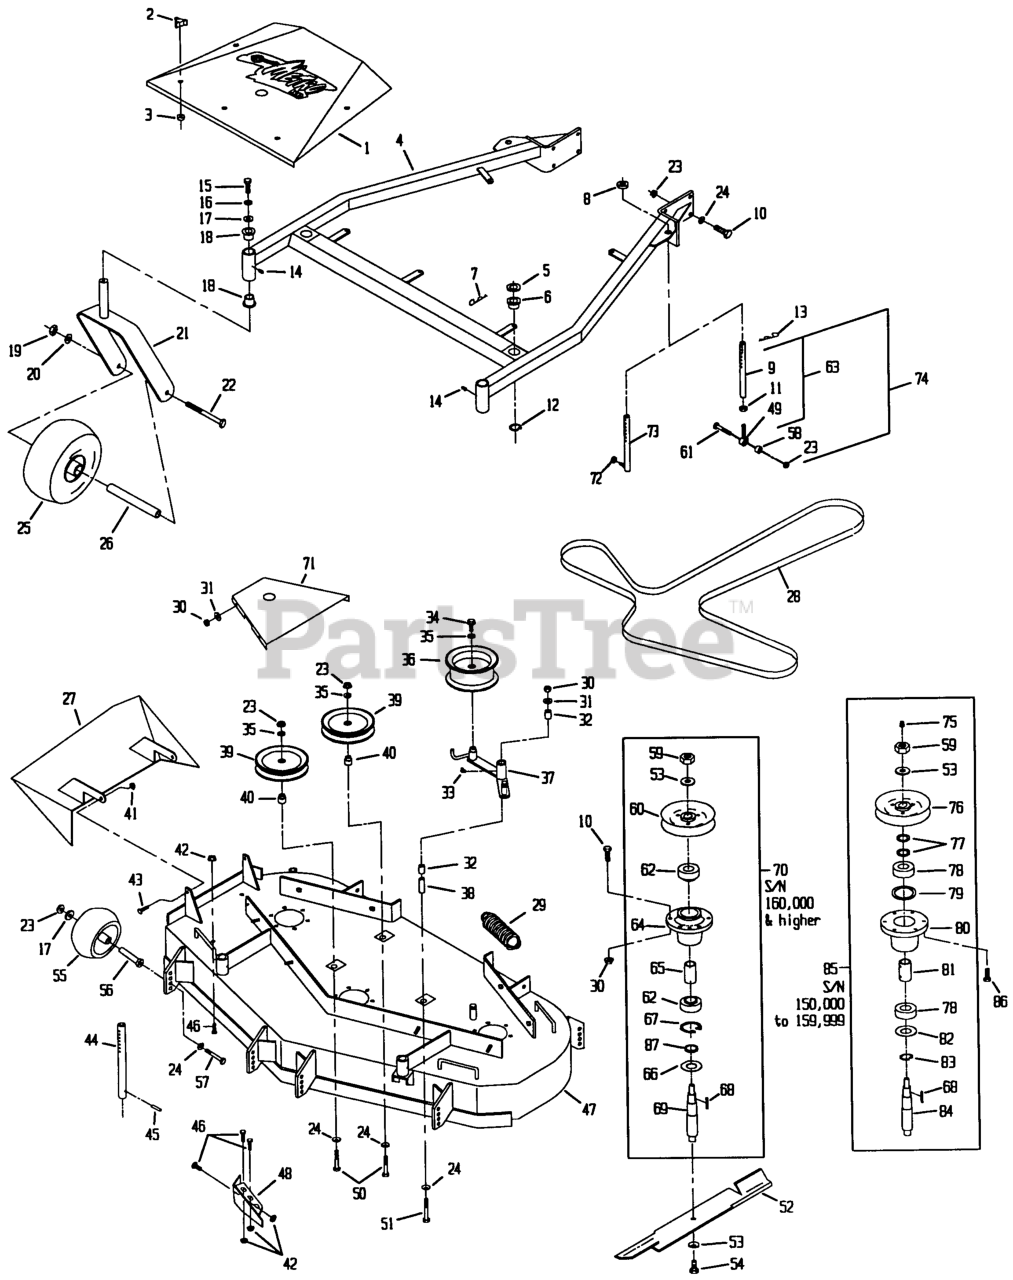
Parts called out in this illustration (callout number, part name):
1	SHIELD W/DECAL,MHP52
2	KNOB-3 PRONG
4	SUPPORT,DECK W/BUSHINGS
5	SPACER-DECK SUPPORT
6	BUSHING-DECK
9	LINK, DECK SUPPORT
13	PIN,HAIR COTTER
18	BEARING-FLANGED
27	WLD,CHUTE DISCHARGE
28	BELT,DECK DRIVE
32	SLEEVE-BEARING
38	BUSHING-PIVOT, IDLER
39	PULLEY-IDLER
40	BUSHING-IDLER
44	ROD,DECK SUPPORT
47	ASM,DECK W/DECALS TTHP52
48	WLD,BAFFLE DISCHARGE
49	BALLJOINT
51	SCREW-HH
53	WASHER-SPRING
55	ROLLER-SCALP, ANTI
56	BUSHING-ROLLER
60	SHEAVE,W/HUB 5.72
62	BEARING
65	SPACER-BEARING
66	GUARD-BEARING, BOTTOM
68	KEY-RECTANGLE
69	SHAFT,SPINDLE
70	HOUSING,CUTTER COMPLETE
73	Link
76	SHEAVE,W/HUB 5.72
77	WASHER-SPACER
78	BEARING,HD SPINDLE
79	O-RING
80	HOUSING,BEARING
81	SPACER,BEARING
82	SEAL,MECHANICAL DUST
83	RING,SNAP WLDS N5000-244
85	Housing, Cutter Assembly
86	SCRW,TPTTE HH
87	SPACER-PULLEY/BEARING
